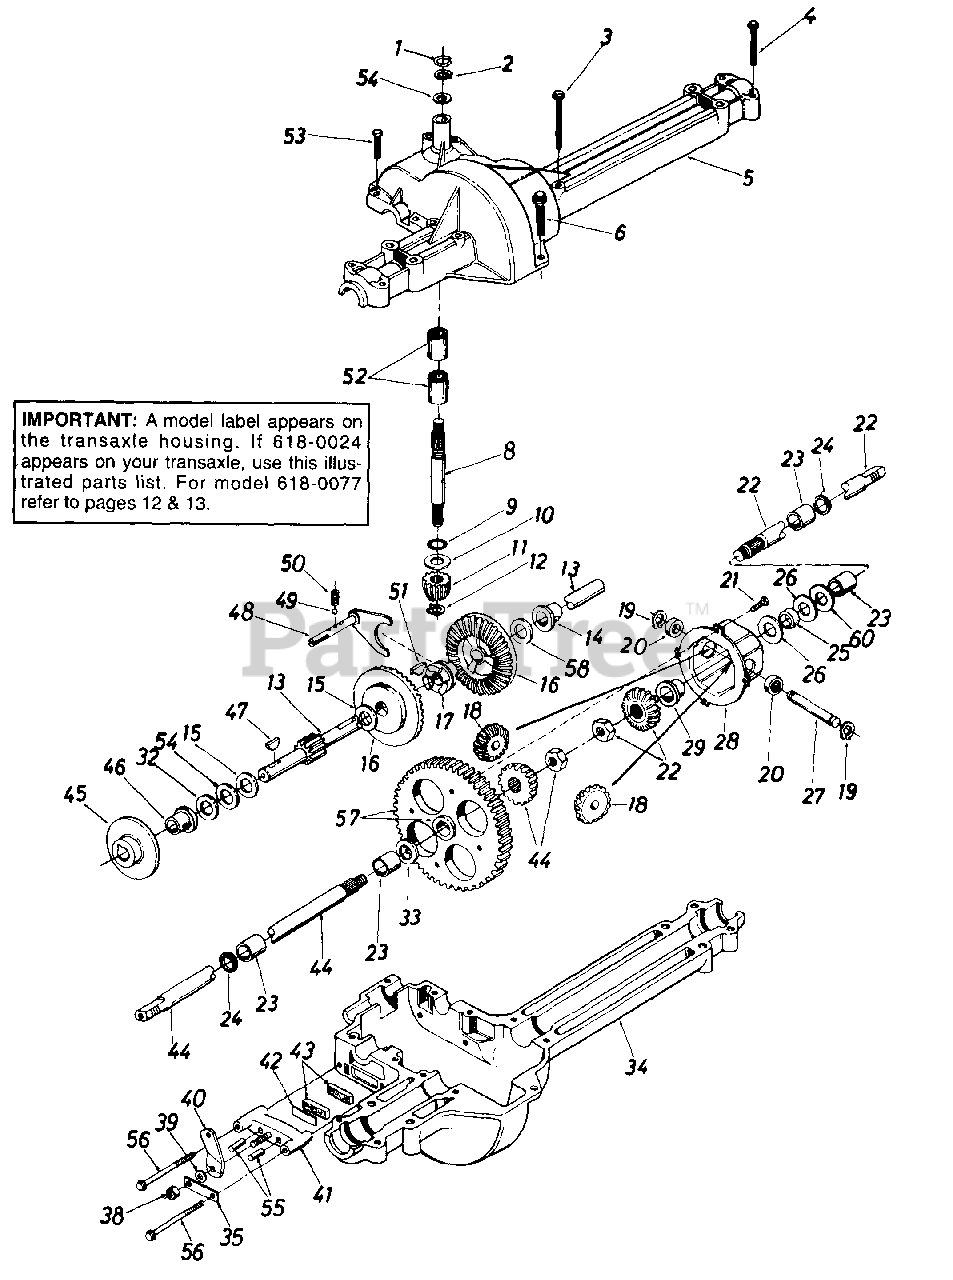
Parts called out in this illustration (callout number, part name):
2	Retaining - Ring
3	Hex Bolt 1/4-20 x 1.75" Lg.
4	Hex Tap Scr. 1/4-20 x 1.25" Lg.
5	Upper Housing
6	Hex TT-Tap Scr. 1/4-20 x .75" Lg.
9	Square Seal 5/8" I.D.
10	Thrust Washer 5/8" I.D. x 1.25" O.D.
11	Pinion Input 14T
12	Retaining Ring
14	Flange Brg. 5/8" I.D. x 3/4" Lg.
15	Fl-Wash. 5/8" I.D. x 1.25"
16	Bevel Gear 42T
17	Clutch Collar
18	Miter Gear 15T (H.D.)
19	Snap Ring
20	Thrust Bearing
21	Pan Head Scr. 1/4-20 x .50" Lg. w/Patch
22	Axle R.H. Ass'y.
23	Sleeve Bearing 3/4" I.D. x 1.0" Lg.
24	Oil Seal 3/4" I.D.
26	Fl-Wash. .760" I.D. x 1.5" O.D.
28	Differential Can Ass'y.
32	Thrust Wash. 5/8" I.D. x 1" O.D. x .025" Thk.
33	Fl-Wash. .760" I.D. x 1.5" O.D.
34	Lower Housing
35	Anti-Rotation Brkt.
38	Hex Nut 5/16-24 Thd.
39	Fl-Wash. .344" I.D. x .875" O.D.
40	Actuating Arm
41	Brake Yoke
42	Puck Plate
43	Brake Puck
44	Axle L.H. Ass'y.
46	Flange Bearing 5/8" I.D. x 15/16" Lg.
47	Woodruff Key 3/16 x 5/8 HT
48	Shift Fork Ass'y.
49	Ball Detent .250" Dia.
50	Spring Detent
51	#9 Hi-Pro Key 3/16" x 3/4" Dia, HT
52	Needle Brg. 5/8" I.D. x 1/2" Lg.
53	Hex Bolt 1/4-20 x 1.00" Lg.
54	Fl-Wash. 5/8" I.D. x 1" O.D. x .020 Thk.
55	Actuating Pin 5/16" Dia.
56	Hex Wash Hd. Self-Tap Scr. 1/4-20 Thd.
57	Differential Gear 72T Ass'y. w/Bearing
58	Fl-Wash. 5/8" I.D. x 1" O.D. x .020 Thk.
60	Fl-Wash. .76" I.D. x 1.5" O.D. x .010" Thk.
